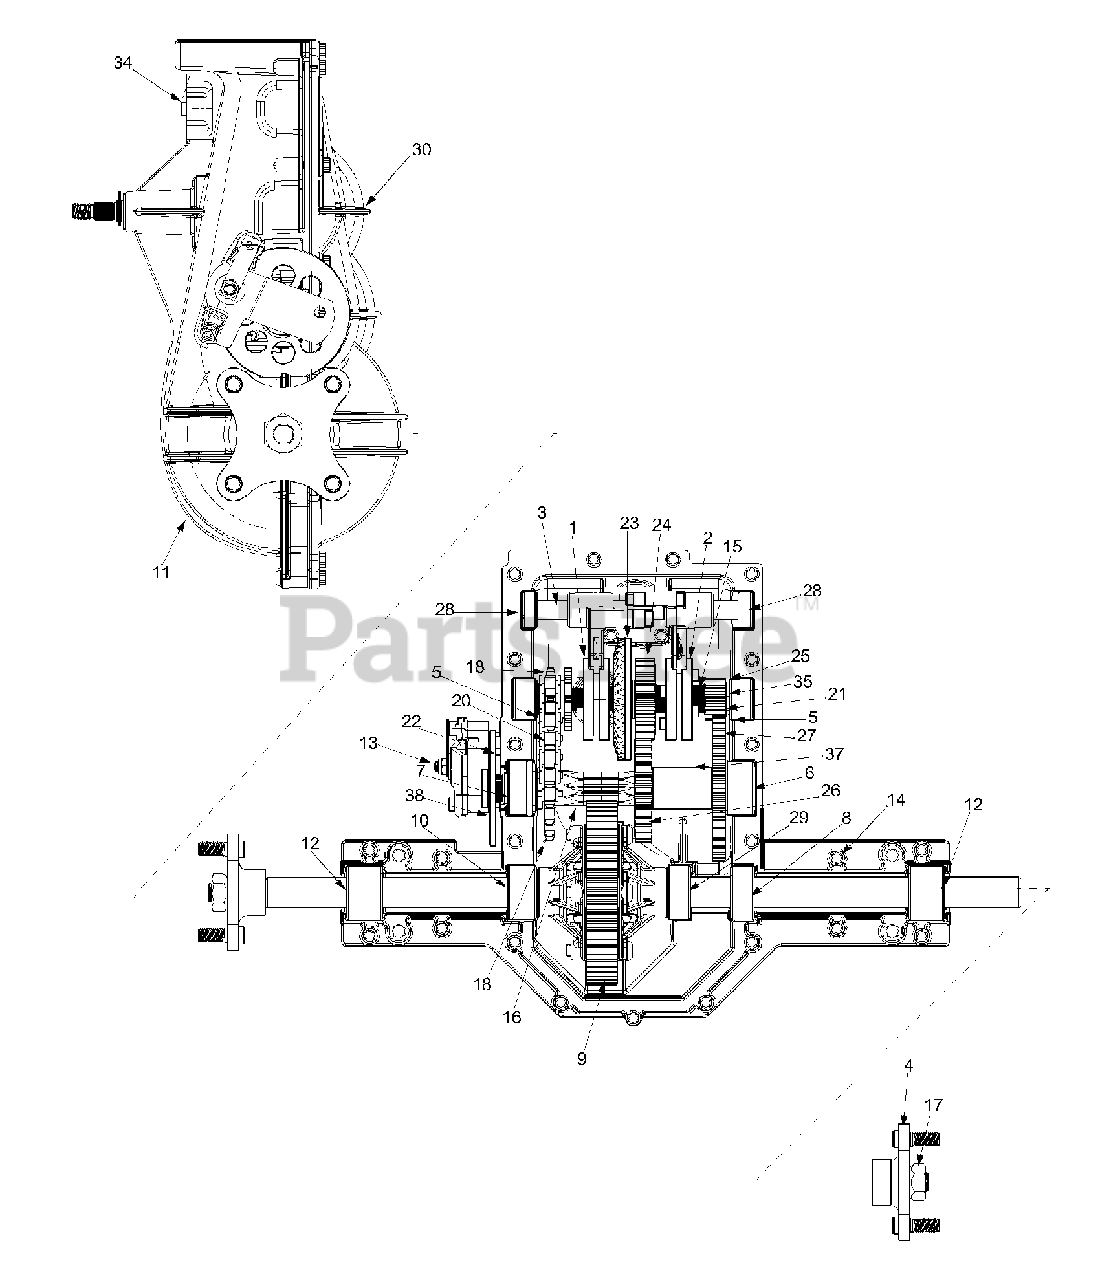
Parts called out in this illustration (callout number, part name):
1	Collar Assembly-Reverse
2	Collar Assembly-Hi-Lo
3	Shift Fork Assembly
4	Wheel Hub Assembly
5	Drive Shaft Blk. Assembly
6	Output Brg. Blk. Assembly
7	Output Brg. Blk. Seal
8	Inboard Axle Blk. Assembly
9	Differential Axle Assembly
10	Inboard Axle Blk. Assembly
11	Upper Housing Assembly
12	Axle Brg. Blk. Assembly
13	Bracket Assembly -RH
14	TT-Tap Scr. 1/4-20 x 1"
15	Drive Shaft
16	Output Shaft -RH
17	Hex Nut 3/4-16
18	Sprocket 9T
20	Chain Endless
21	Ext. Snap Ring
22	Brake Pad
23	Bevel Gear 41T
24	Spur Gear 20T
25	Spur Gear 10T
26	Spur Gear 27T
27	Spur Gear 37T
28	Shifter Brg. Blk.
29	Inner Axle Blk. Brg.
30	Lower Housing
34	Shipping Plug
35	Flat Washer 5/8" I.D. x 1" O.D.
37	Spacer 1.13" I.D. x 1.38" O.D.
38	Disc Brake
